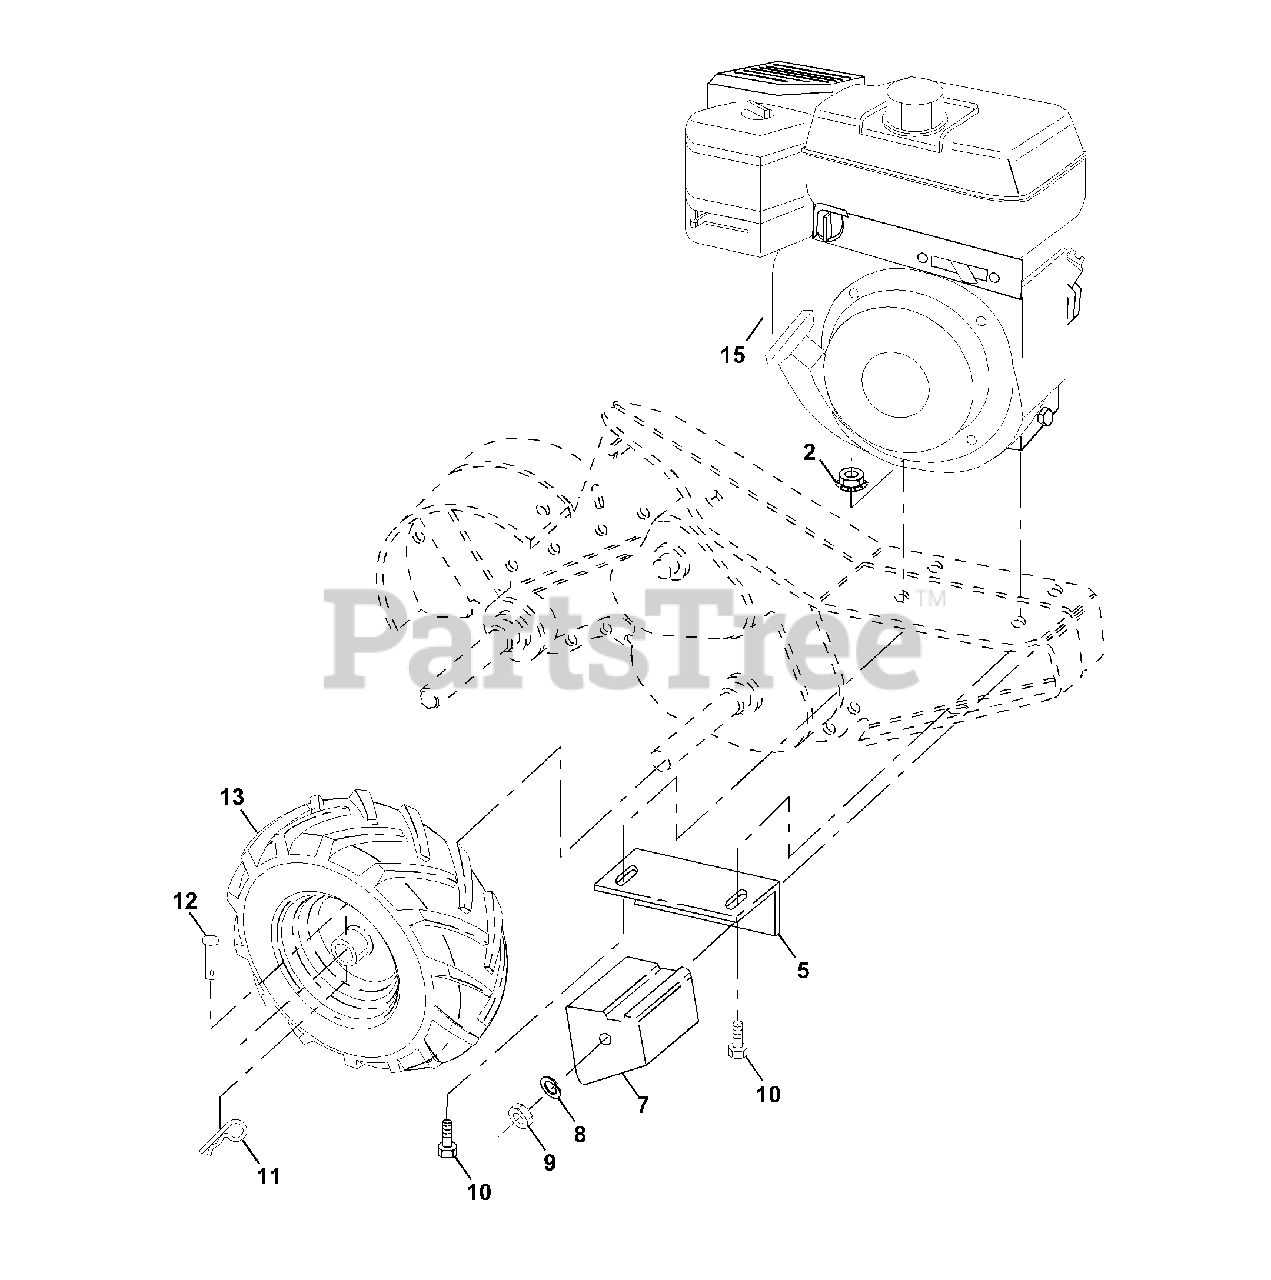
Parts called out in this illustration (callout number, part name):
2	Nut, Lock Hex Flange
5	Bracket, Reinforcement
7	Counter Weight, R.H.
8	Washer, Lock 3/8
9	Nut, Hex 3/8-16
10	Bolt, Hex 5/16-18 x 1-1/2
11	Clip, Hairpin
12	Rivet, Drilled
13	Tire
13	Tire Valve
